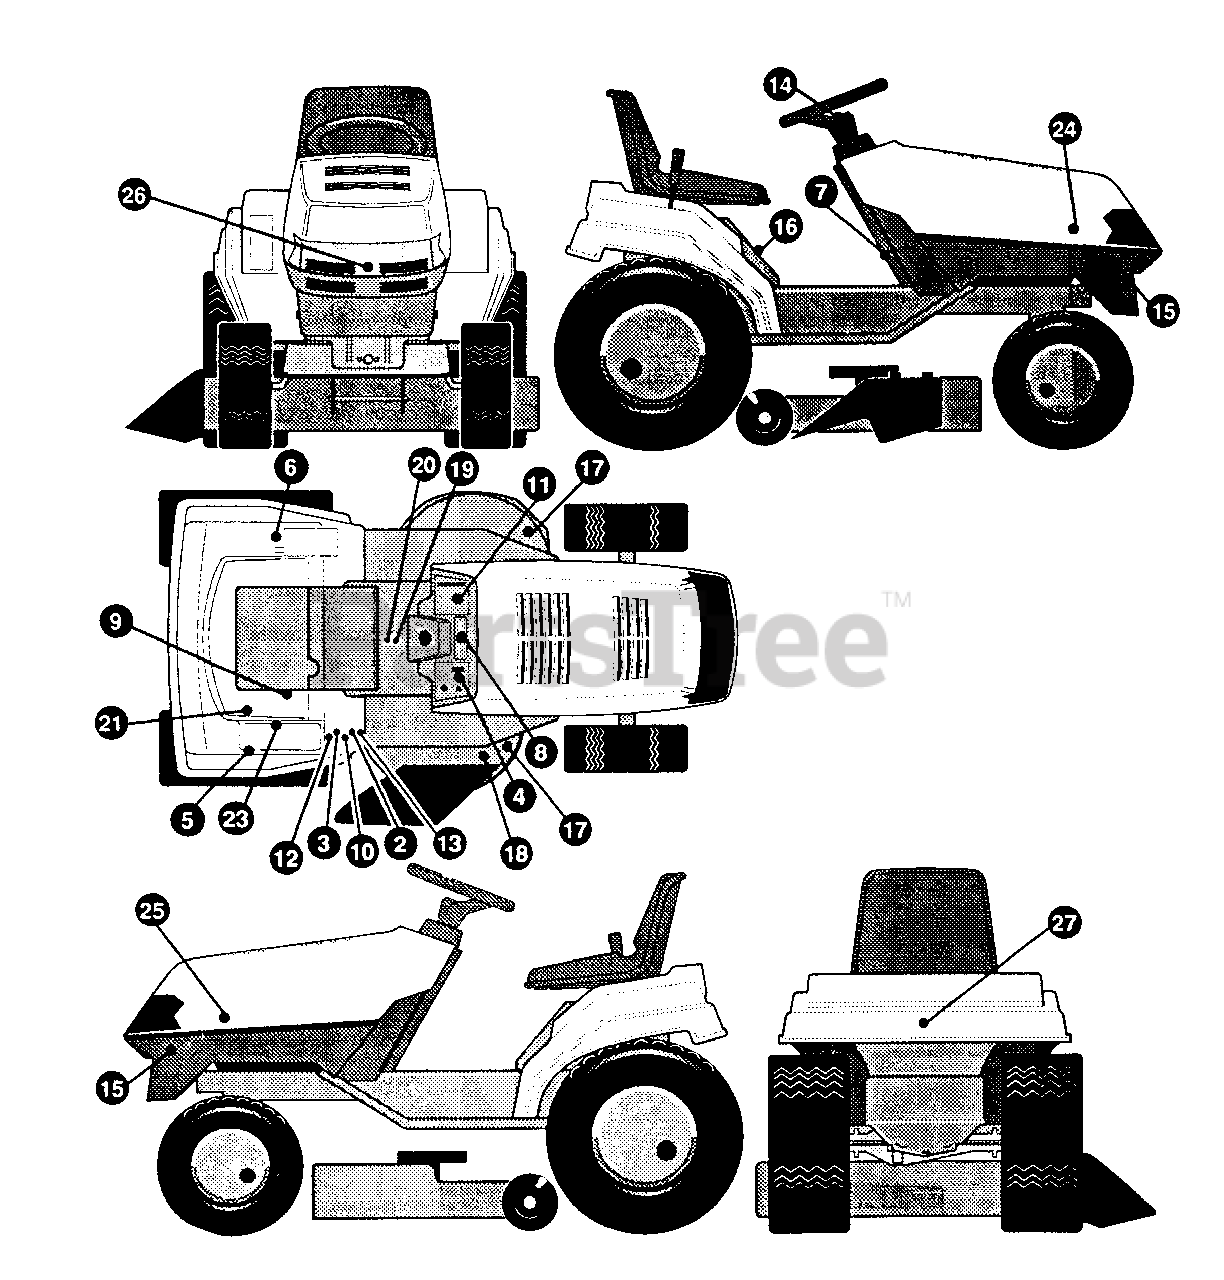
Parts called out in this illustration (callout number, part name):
1	REFERENCE ONLY
2	DECAL,CAUTION TRIANGLE EUROPE
3	DECAL.DANGER FRENCH
4	DECAL DASH RH ISO CH,HR,LS,IS
5	DECAL SHIFT INDICATOR EXPORT
6	DECAL,EXPORT BL.CL. @ DECK HT
7	DECAL PARK BRAKE EXPORT
8	DECAL,DASH OIL,FUEL, ASG,NO CHG
9	DECAL,CERT.DE CONFORMITE 1994
10	DECAL,DANGER ENGLISH
11	DECAL DASH LH ISO,AMM,M/CL,M/CH
12	DECAL,DANGER GERMAN
13	DECAL,DANGER CONS SIDE SWEDISH
14	DECAL, GUNSIGHT CENT. 3 SPOKE
15	DECAL, WHEEL 4 STEER HUSQ. BUM
16	DECAL, LAWN TRACTOR SEAT SUPP
17	DECAL, WARN 11/LANG HANDS/FEET
18	DECAL, WARN DEF SHLD 11 LANG
19	DECAL, START INSTCONS 11LANG
20	DECAL. ENTER & EXIT 11/LANG
21	DECAL, 4WS PATENT NO. 5048853
22	REFERENCE ONLY
23	DECAL GEAR SHIFT 6 SPEED ERO
24	DECAL. HOOD HUSOVARNA RH
25	DECAL. HOOD HUSOVARNA LH
26	DECAL. GRILLE HUSQVARNA
27	DECAL, REAR FENDER HUSOVARNA
28	DECAL,TUV GS
30	DECAL.ENGINE 14BS V-TWIN 2YR
